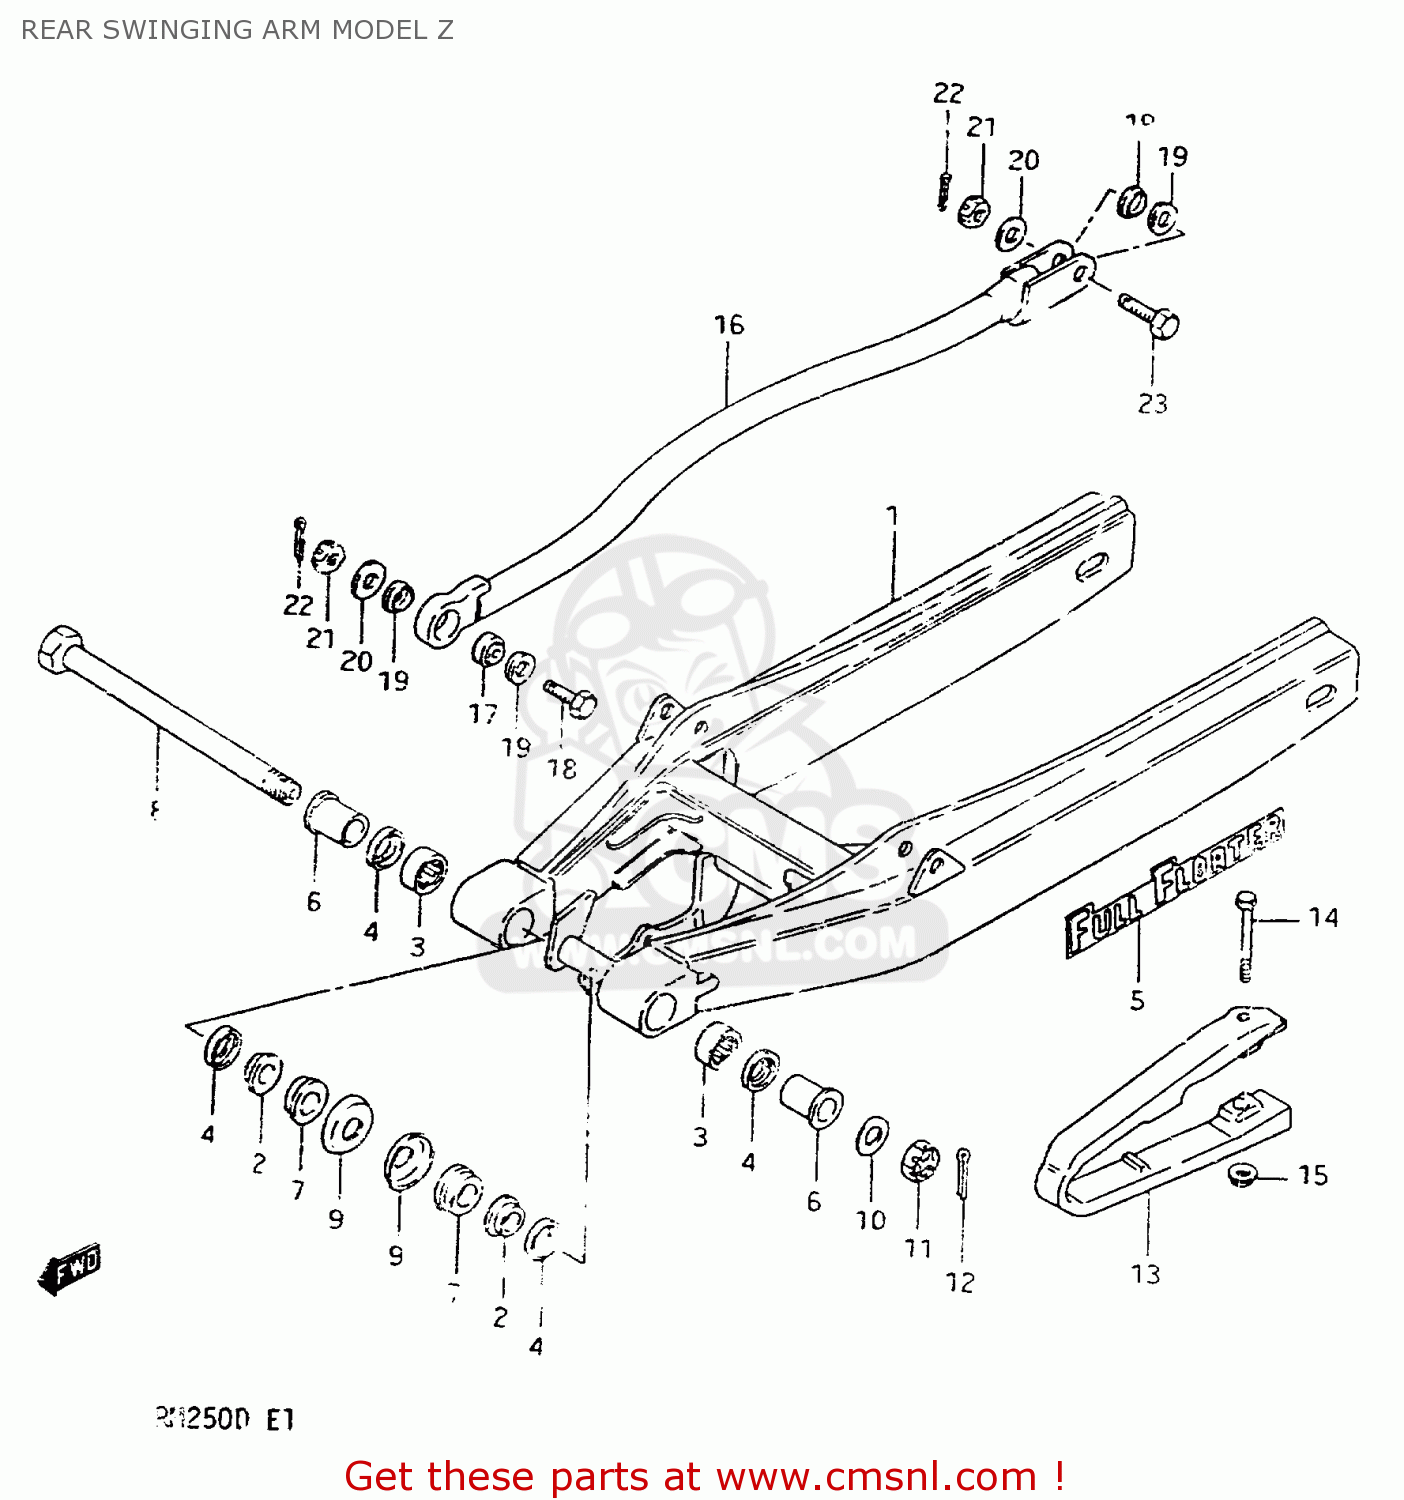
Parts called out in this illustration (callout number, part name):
1	SWING ARM ASSEMBLY,REAR
2	BUSH,RR SWINGINGARM PIVOT
3	BEARING(20X27X20)
4	OIL SEAL
5	EMBLEM,SWING ARM
6	SPACER,RR SWGARM PIVOT
7	SPACER,RR SWGARM PIVOT INNER
8	SHAFT,RR SWINGINGARM PIVOT
9	COVER,RR SWGARM DUST SEAL
10	WASHER
11	NUT 14MM
12	COTTER PIN
13	BUFFER,CHAIN TOUCH DEFENSE
14	BOLT(6X70)
15	NUT
16	LINK,REAR TORQUE
17	SPHERICAL BEARING,TORQUE
18	BOLT 8X28
19	20
20	WASHER
21	NUT 8MM
22	PIN 20X20
23	BOLT 8X29.5
